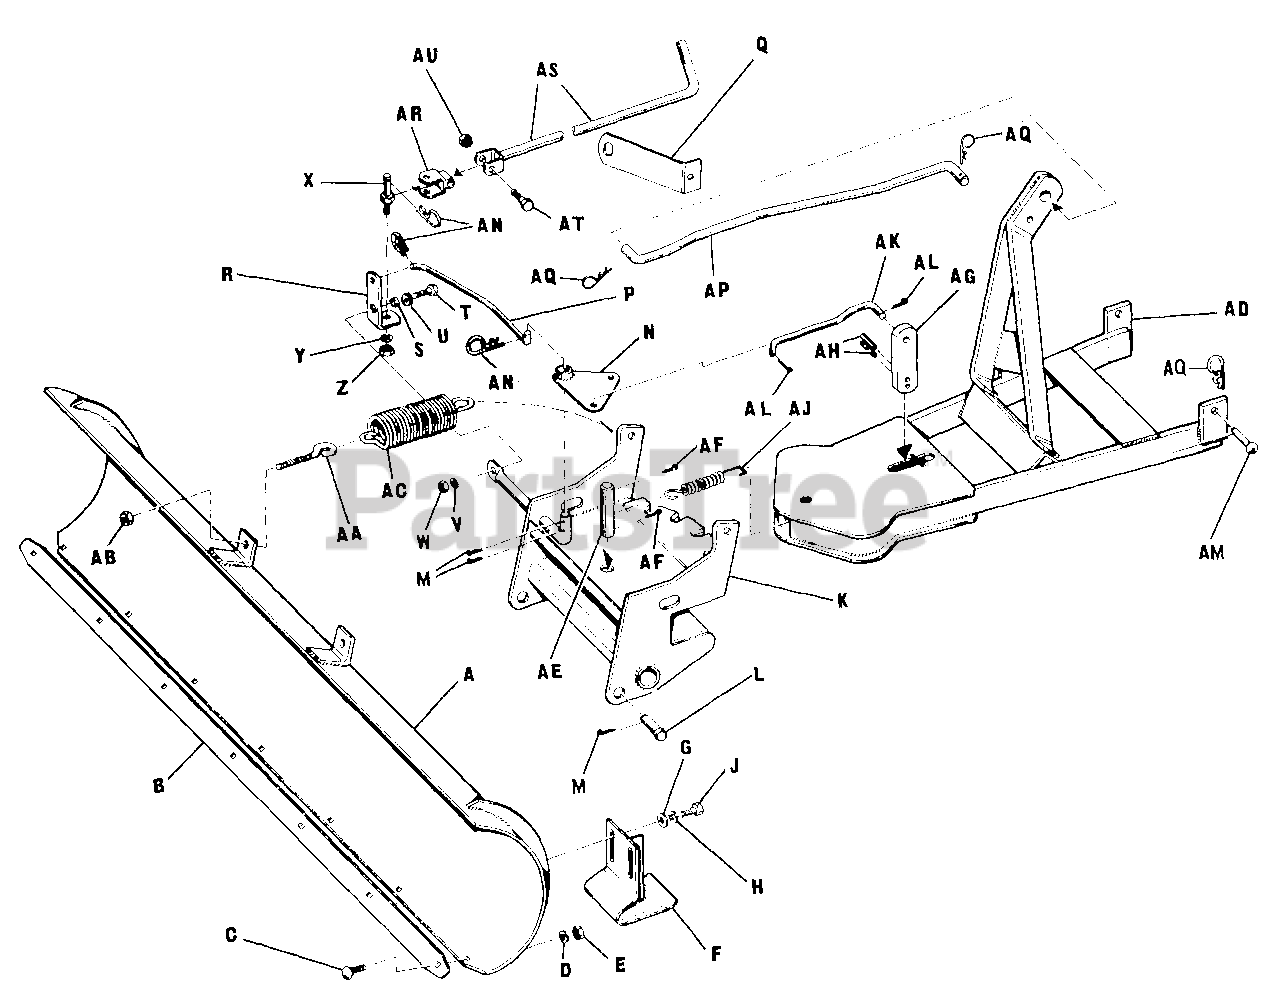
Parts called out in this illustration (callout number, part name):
A	Blade Ass'y
C	Carriage Bolt, 3/8"-16 x 1" lg.
D	Lock Washer 3/8"
E	Full Hex Nut 3/8"-16 N.C.
F	Shoe Ass'y.
G	Flat Washer 3/8"
H	Lock Washer 3/8"
J	Hex. Cap Screw 3/8"-16 x 3/4"
K	Pivot Frame Ass'y
M	Cotter Pin 1/8 Dia. x 1"
N	Pivot Plate Ass'y
R	Pivot Arm
T	Hex Cap Screw 5/16"-18 x 1" lg.
U	Plain Washer 5/16"
V	Lock Washer 5/16"
W	Full Hex. Nut 5/16"-18 N.C.
Y	Lock Washer 5/16"
Z	Full Hex. Nut 5/16"-18
AB	Full Hex. Nut 5/16"-18
AD	Push Bar Ass'y
AE	Pivot Pin 5/8" Dia. x 3-3/8" lg.
AF	Cotter Pin 3/16 x 1-1/4" lg.
AH	Roll Pin 7/32" Dia. x 1" lg.
AJ	Latch Spring
AL	Cotter Pin 3/32" Dia. x 5/8"
AM	(Hitch) Pin
AN	Spring Clip
AP	Front Lift-Rod
AQ	Spring Clip
AS	Handle Ass'y
AT	Hex. Cap Screw 5/16"-18 x 1-1/2"
AU	Full Lock Hex. Nut 5/16"-18
